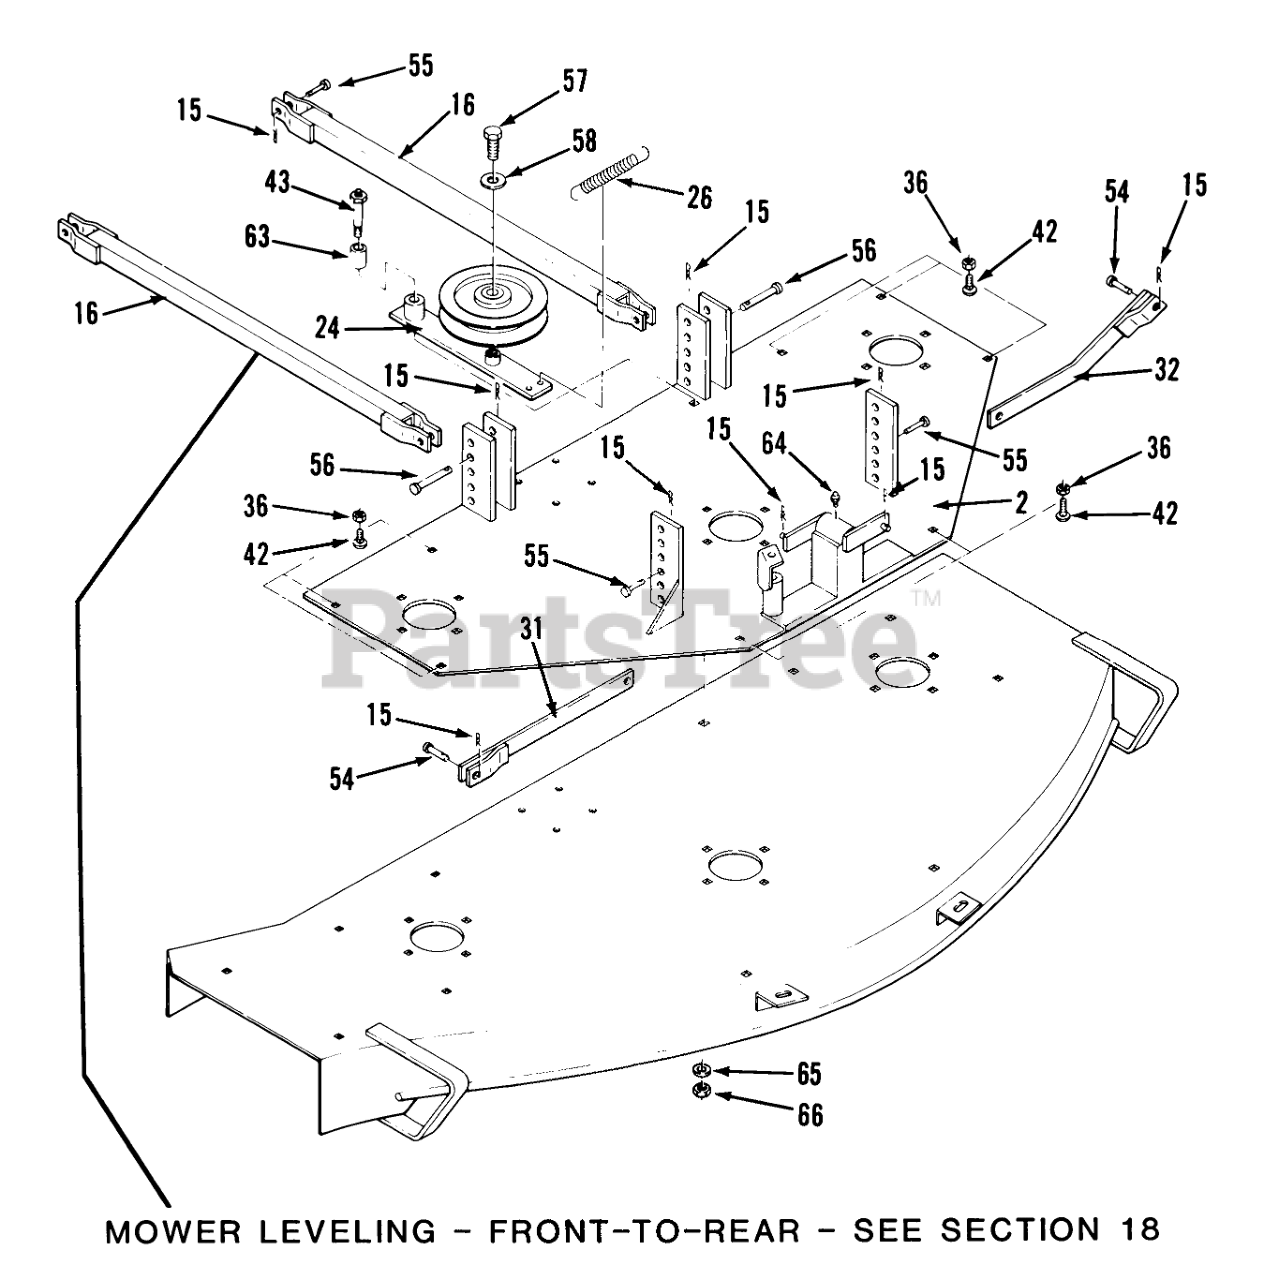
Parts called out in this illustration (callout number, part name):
2	Mower Deck Plate
2	Washer
15	HAIRPIN
16	Stabilizer Bar
24	ARM-IDLER 30223-87
26	SPRING TENSION
31	STABILIZER RH
32	LH Stabilizer
36	Nut
36	NUT
42	Bolt
42	Bolt-Carriage
43	Shoulder Bolt 1/2-13 x 1 3/4/w Grease Fitting
54	PIN CLEVIS 5/16X1
55	Clevis Pin 3/8 x 1 1/4
56	Clevis Pin 3/8 x 2 1/4
57	Bolt
58	Lockwasher
63	Bronze Bushing
64	Zerk
65	Washer
66	NUT
